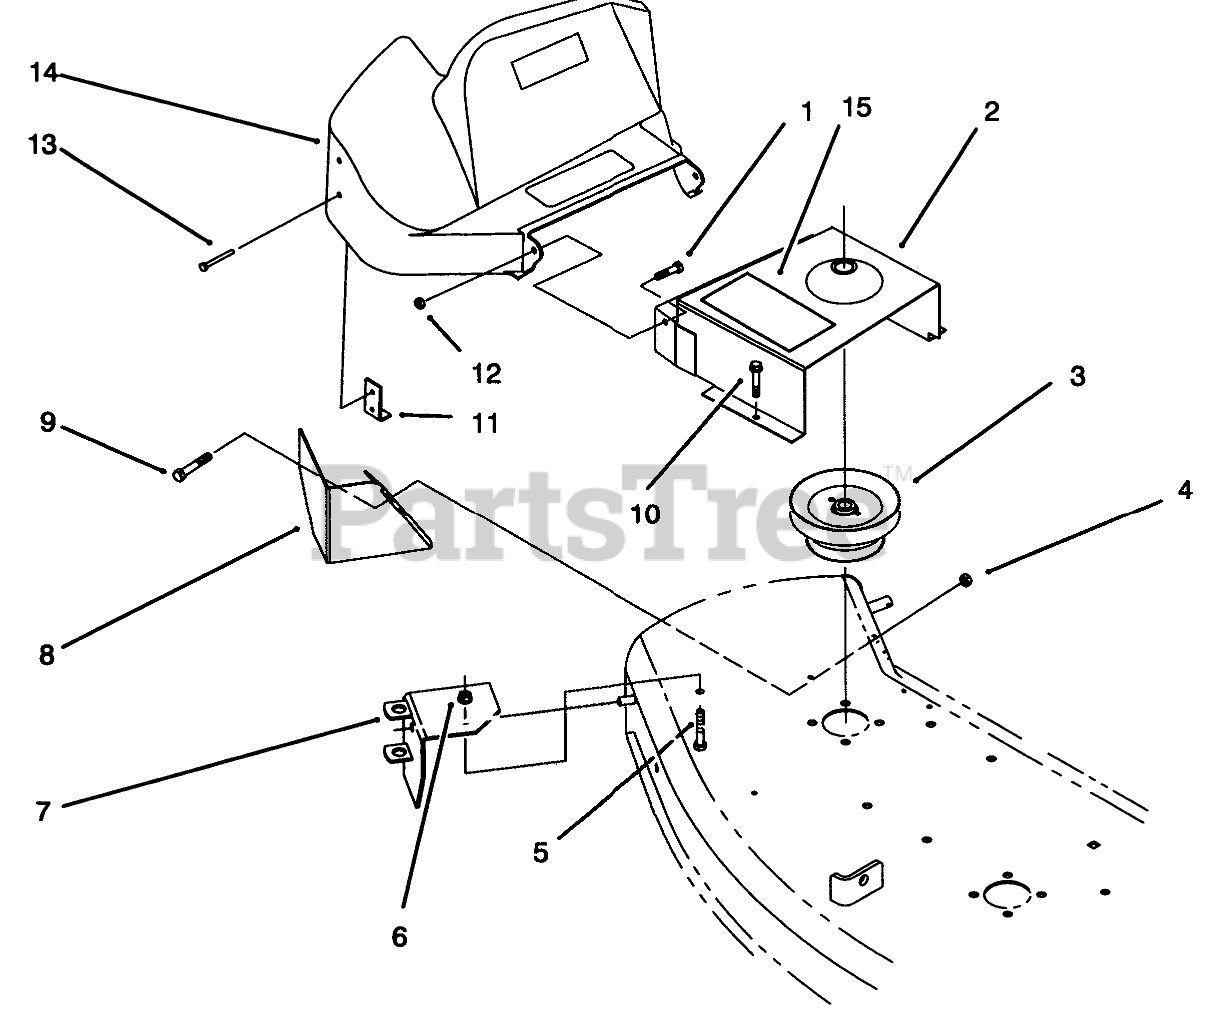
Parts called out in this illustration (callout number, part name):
1	SCREW-HH
2	48" Inner Shield Assembly (Incl. Ref. #15)
3	PULLEY
4	NUT-LOCK, NI
5	SCREW-HH
6	NUT-HF
7	PIVOT SUPPORT ASM
8	48" DEFLECTOR B
9	SCREW-CARR
10	Bolt
11	BRACKET-SUPPORT, SHIELD
12	NUT-LOCK, NI
13	RIVET-POP
14	SHIELD-BELT
15	DECAL-DANGER
